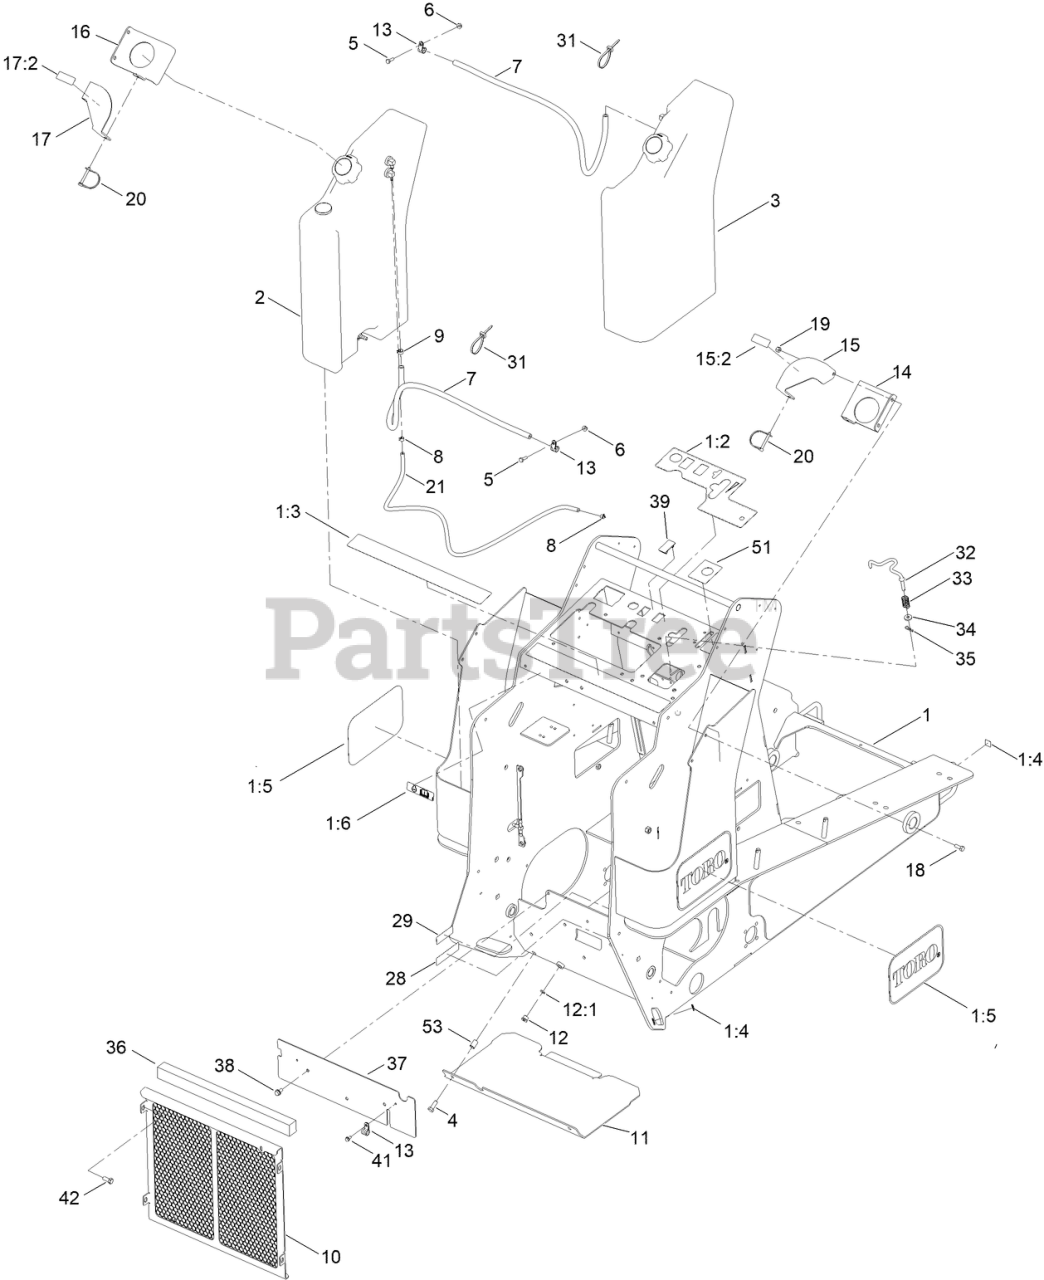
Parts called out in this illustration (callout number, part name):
1	TX1000 FRAME ASM (SERVICE)
1:2	DECAL-CONTROL PANEL
1:3	DECAL-SAFETY
1:4	DECAL-POINT, LIFT
1:5	DECAL
1:6	DECAL-RADIATOR FILL
2	LH FUEL TANK ASM
3	RH FUEL TANK ASM
4	SCREW-HH
5	SCREW-HH
6	NUT-HF
7	HOSE-FUEL
8	CLAMP-HOSE
9	CLAMP-HOSE
10	RADIATOR COVER ASM
11	COVER-BOTTOM
12	PLUG-HEX, HOLLOW
12:1	O-RING
13	CLAMP-R
14	PLATE-HOLD DOWN, RH
15	PLATE-LOCK, FUEL CAP, RH
15:2	DECAL-DIESEL
16	PLATE-HOLD DOWN, LH
17	PLATE-LOCK, FUEL CAP, LH
17:2	DECAL-DIESEL
18	SCREW-HH
19	NUT-LOCK, NI
20	PIN-HITCH
21	HOSE-FUEL
28	DECAL-ARRESTOR, SPARK
29	DECAL - REGULATORY CE DECAL
31	TIE-CABLE
32	ROD-INTERLOCK
33	SPRING-CONTROL
34	WASHER-FLAT
36	SEAL-FOAM
37	PLATE-COVER
38	SCREW-HWHTF
39	PLUG-HOLE
41	SCREW-HWH
42	SCREW-HH
51	DECAL-IGNITION SWITCH
53	NUT-CLINCH
